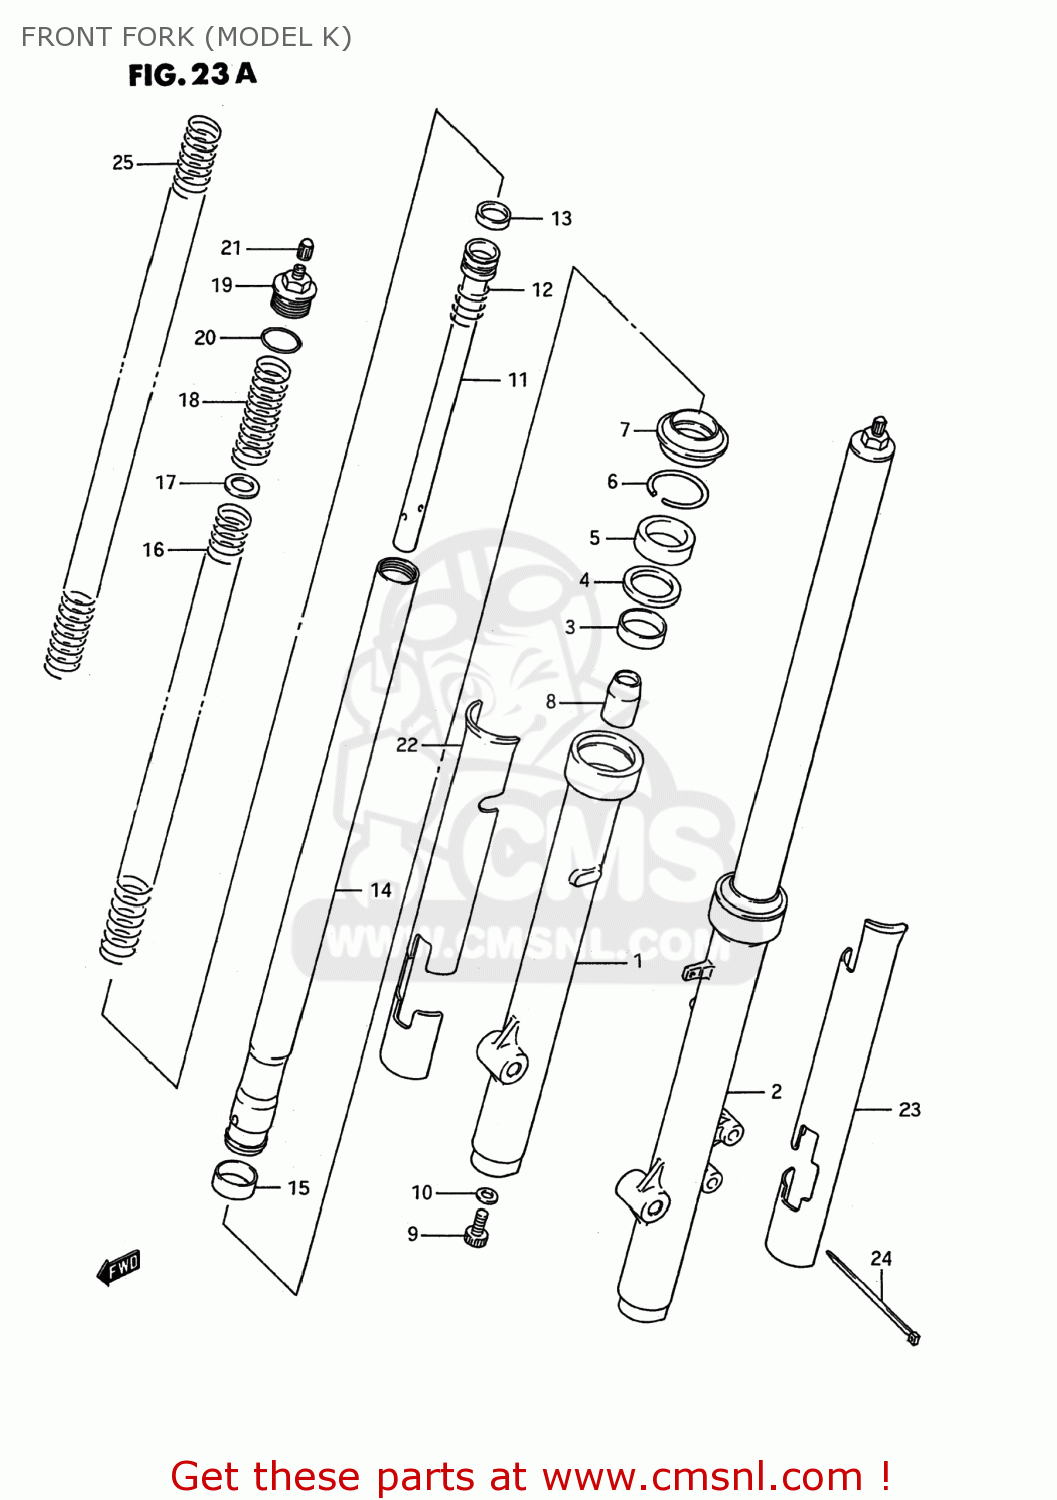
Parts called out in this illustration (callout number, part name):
1	TUBE,OUTER,RIGHT
2	TUBE,OUTER,LEFT
3	BUSH,GUIDE
4	SPACER,SEAL
5	OIL SEAL,FRONT FORK 35X48X11
6	RING,OIL SEAL STOPPER
7	SEAL,DUST
8	PIECE,OIL LOCK
9	BOLT,LWR
10	GASKET,FORK CYLINDER (NAS)
11	SEAT,UNDER
12	SPRING,REBOUND
13	RING,PISTON
14	TUBE,FORK,INNER
15	PISTON
16	O-RING
17	GUIDE,SPRING
18	SPRING,UPPER
19	BOLT,FORK INNER TUBE
20	O RING
21	CAP
22	PROTECTOR,FR FORK,R
23	PROTECTOR,FR FORK,L
24	CLAMP
25	SPRING
